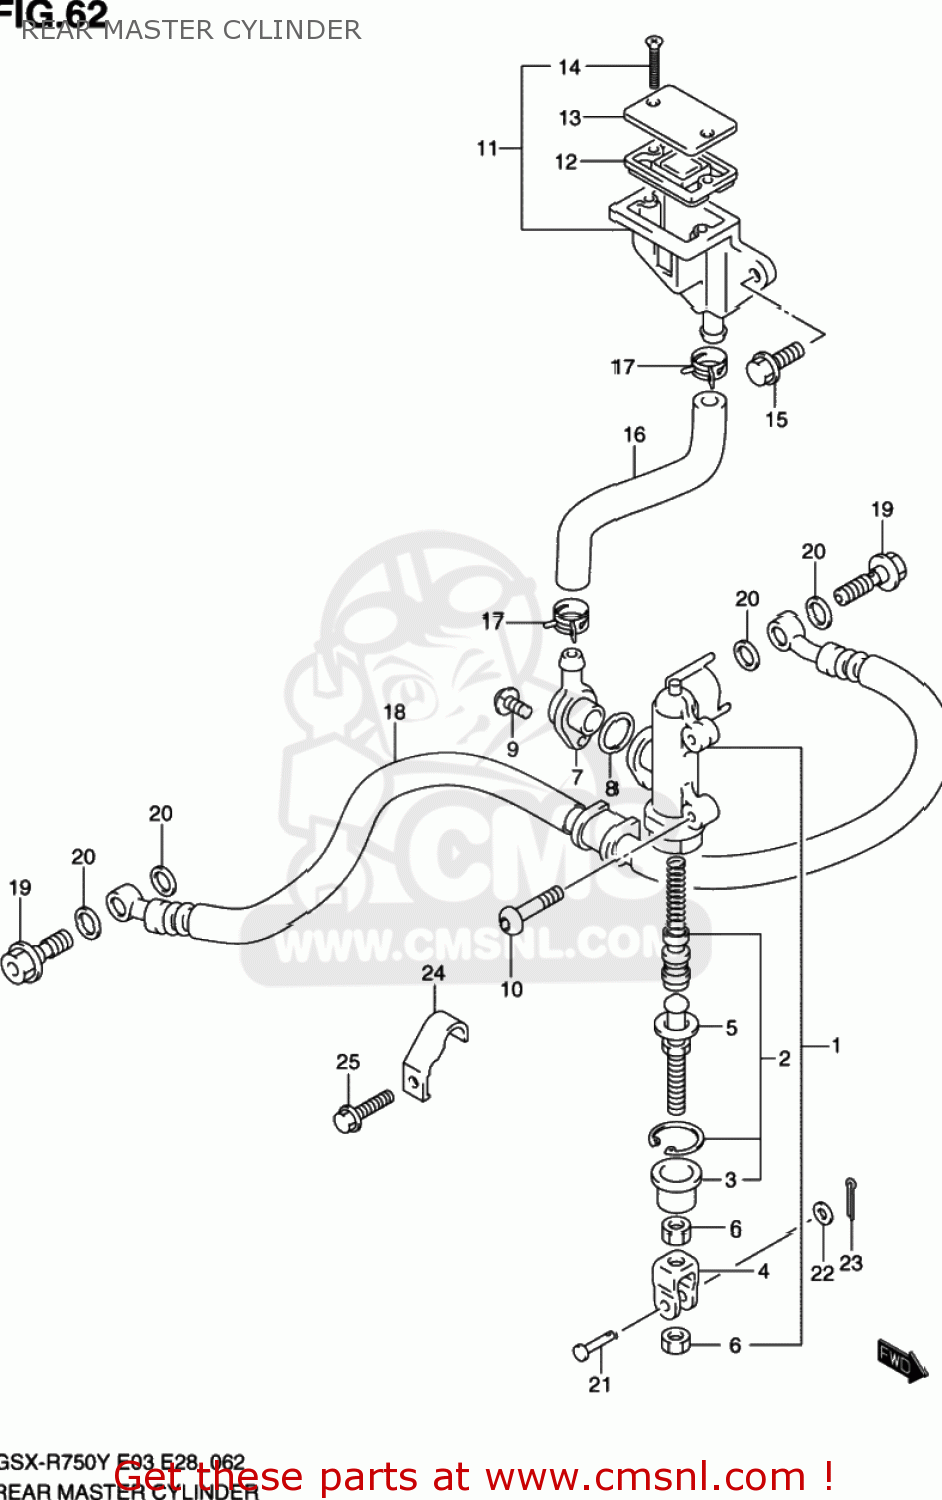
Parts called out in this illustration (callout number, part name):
1	CYLINDER ASSY,RR MASTER
2	PISTON/CUP SET
3	BOOT
4	YOKE
5	ROD,PUSH
6	NUT
7	CONNECTOR
8	O RING
9	SCREW
10	SCREW(6X20)
11	TANK ASSY,RR RESERVOIR
12	DIAPHRAGM
13	CAP
14	SCREW
15	BOLT(6X12)
16	HOSE,RESERVOIR TANK
17	CLIP
18	HOSE,RR BRAKE
19	BOLT UNION
20	WASHER(10X15X1.5)
21	PIN
22	WASHER
23	PIN
24	CLAMP,RR BRAKE HOSE
25	BOLT(6X20)
